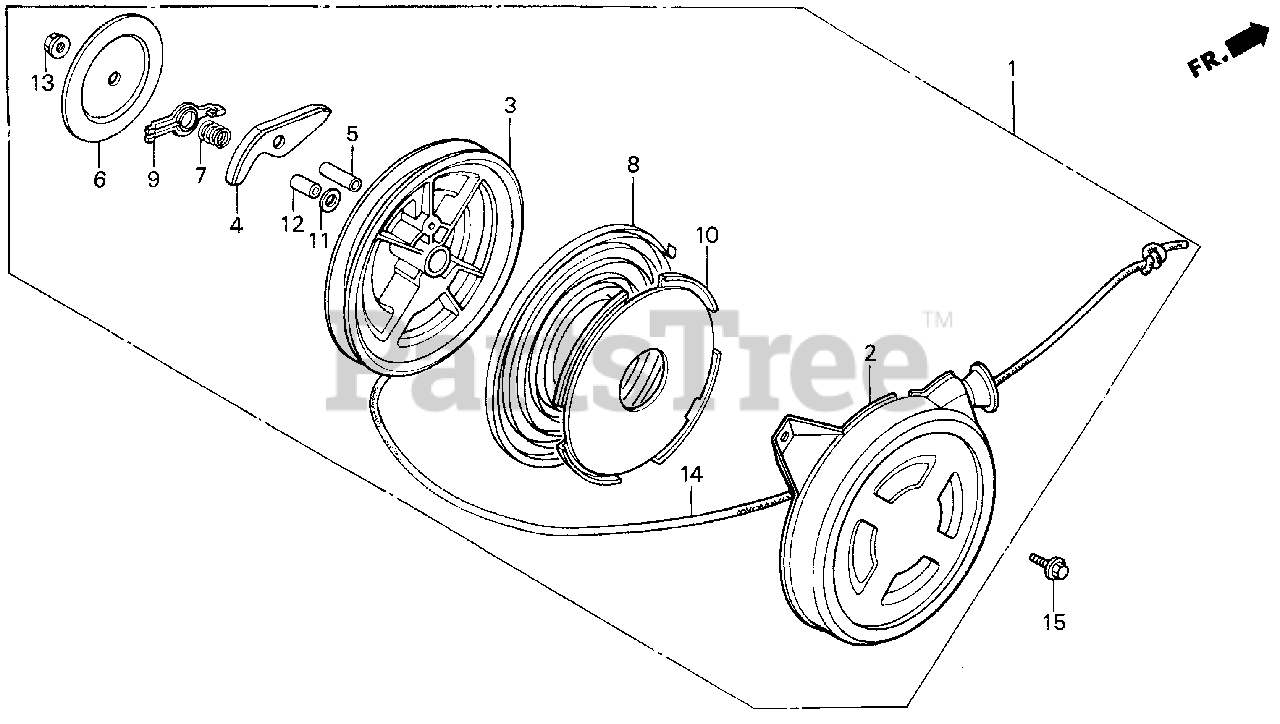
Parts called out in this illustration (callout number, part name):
1	STARTER ASSY., RECOIL *R8* (BRIGHT RED)
2	CASE, RECOIL STARTER *R8* (BRIGHT RED)
3	PULLEY, RECOIL STARTER
4	RATCHET, STARTER
5	PIN, STARTER RATCHET
6	PLATE, FRICTION
7	SPRING, FRICTION
8	SPRING, RECOIL STARTER
9	GUIDE, RATCHET
10	CASE, RECOIL STARTER SPRING
11	WASHER, STARTER
12	SHAFT, SUB
14	ROPE, RECOIL STARTER (#5X59") (NA USE ALT:08550-ZG921-11)
15	BOLT, FLANGE (6X8)
